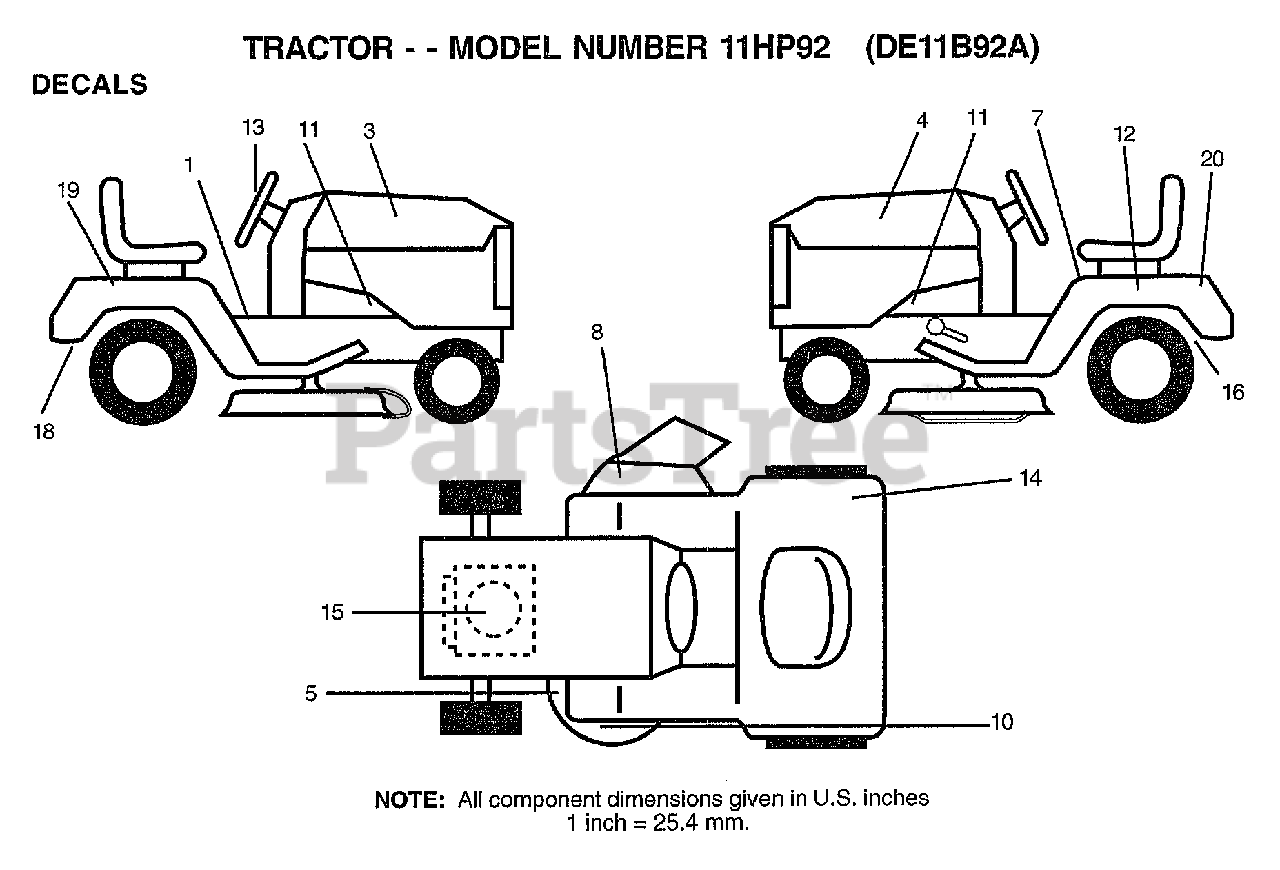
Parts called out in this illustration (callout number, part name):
1	DECAL CLUTCH/BRAK
3	DECAL.HOOD.RH
4	DECAL.HOOD.LH
5	DECAL.V.BELT
7	DECAL.READ.O.MANU
8	DECAL.DANGER.CUTF
10	DECAL.DECK.MOWER
11	"DECAL CHASSIS,HOT"
12	DECAL.BATRY.3-3908
13	DECAL.INST.STEERING
15	DECAL, ENGINE
16	DECAL.DRAWBAR.LDL
18	DECAL.EURO.ST.CE.
19	DECAL, FENDER
20	DECAL, FENDER
